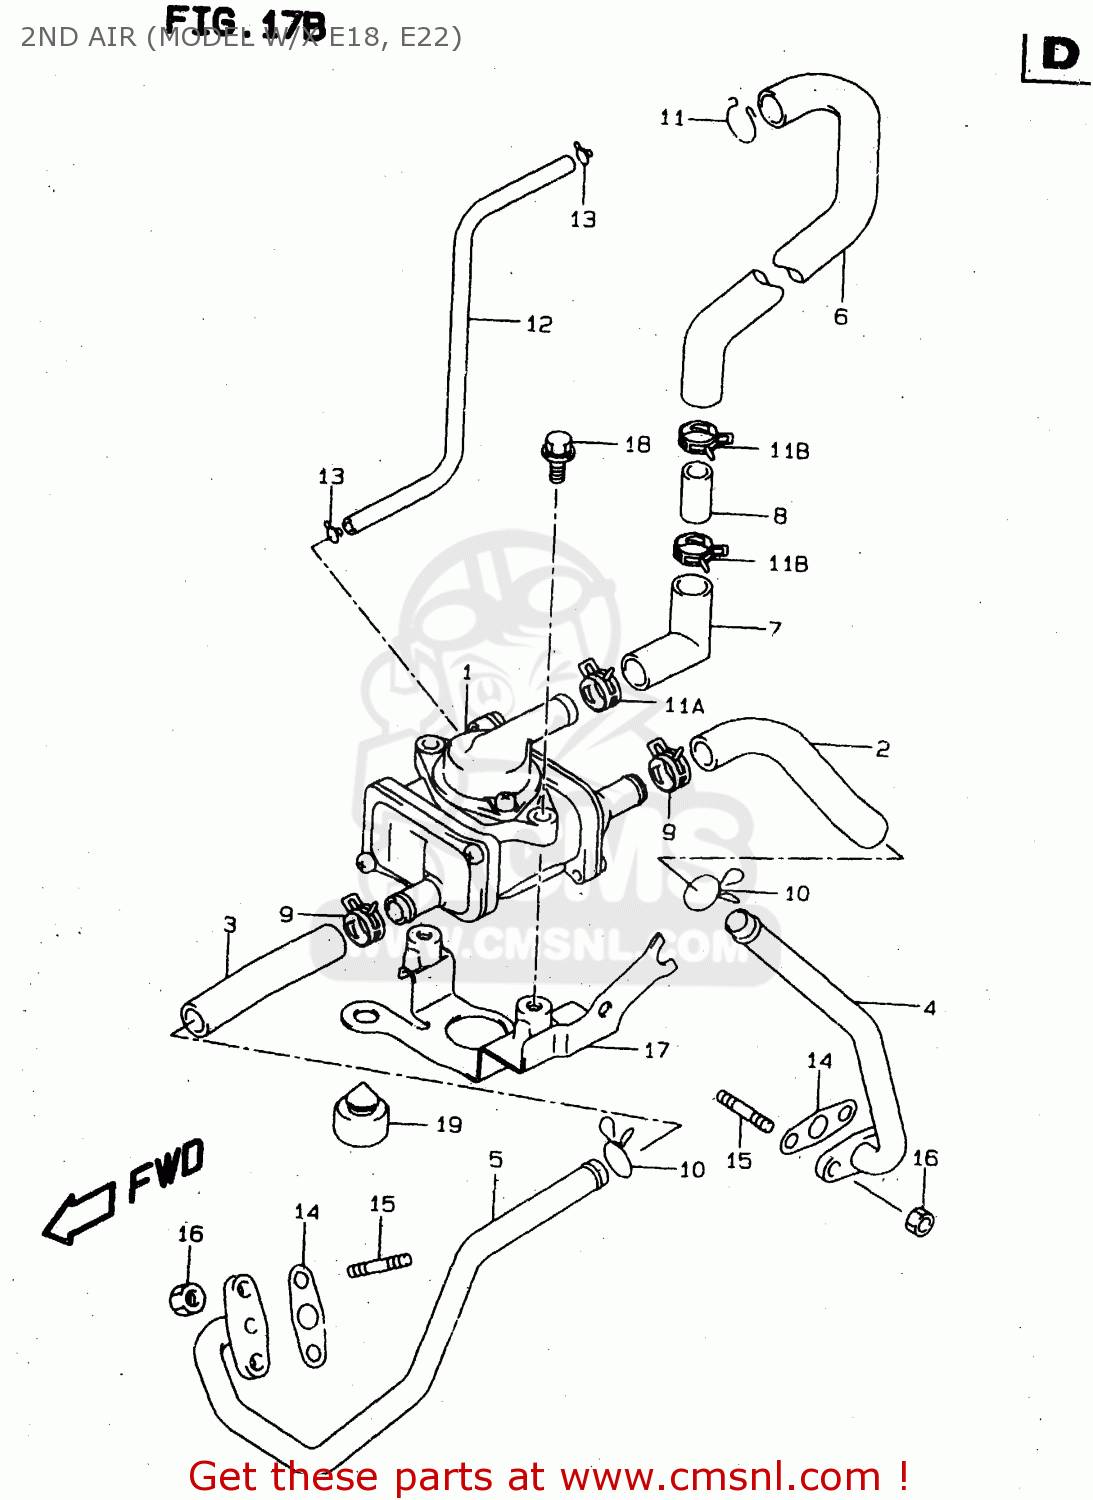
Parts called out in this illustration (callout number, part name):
1	VALVE ASSY,2ND AIR
2	HOSE,2ND AIR VALVE FR
3	HOSE,2ND AIR VALVE RR
4	PIPE COMP,SECOND AIR,FRONT
5	PIPE COMP,SECOND AIR,REAR
6	HOSE,2ND AIR CLEANER
7	HOSE,2ND AIR CLEANER JOINT
8	JOINT,2ND AIR CLEANER HOSE
9	CLIP
10	CLIP
11	CLIP
11A	CLIP
11B	CLIP
12	HOSE(4X7X600)
13	CLIP
14	GASKET,SECOND AIR PIPE (N (NAS)
15	STUD BOLT
16	NUT
17	BRACKET,2ND AIR VALVE
18	BOLT
19	CUSHION(11.5X22X20)
